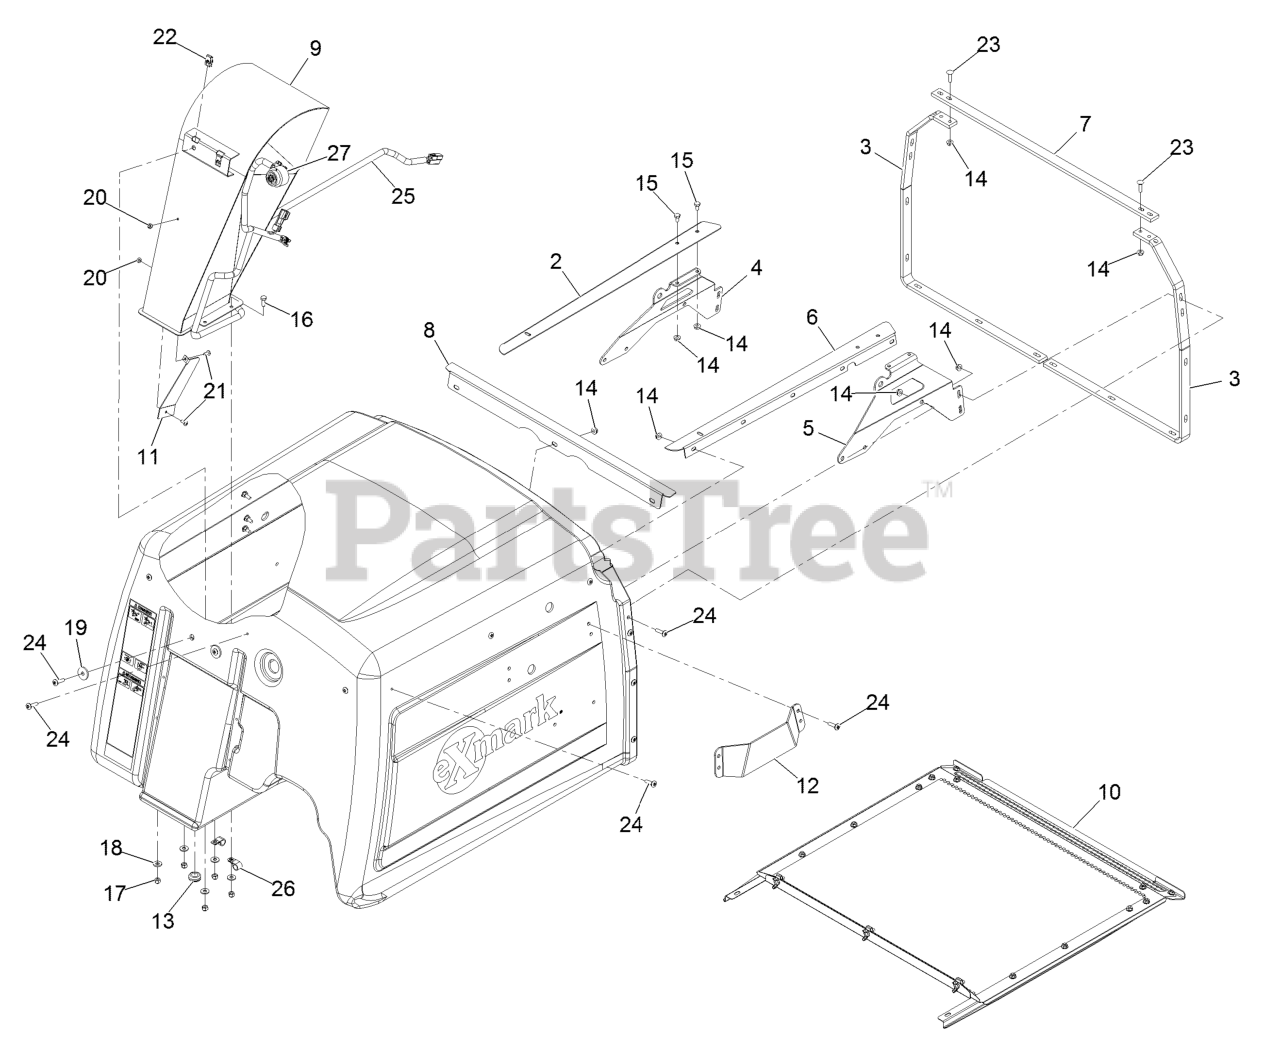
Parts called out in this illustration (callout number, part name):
2	Angle-Screen Track, RH
3	Reinforcement-Hopper
4	Brace-Door Pivot, RH
5	Brace-Door Pivot, LH
6	Angle-Screen Track, LH
7	Bracket-Frame Connect
8	Channel-Screen, Front
10	Hopper Screen ASM
11	Deflector-Discharge Chute
12	Plate-Guard
13	Grommet
14	Nut-Whizlock 1/4-20
15	Screw-HH 1/4-20 X 1/2
16	Screw-HH 1/4-20 X 3/4
17	Nut-Nyloc 1/4-20
18	Washer-1/4 Std
20	Nut-Nyloc #10-24
21	Screw-Truss HD #10-24 X 1/2
22	Nut-Retainer-Panel 1/4-20
23	Bolt-Carriage 1/4-20 X 1
24	Screw-Truss HD 1/4-20 X 1
25	Harness-Wire, Hopper
26	Clip-Loom 1/2
27	Alarm-Tone, Dual
